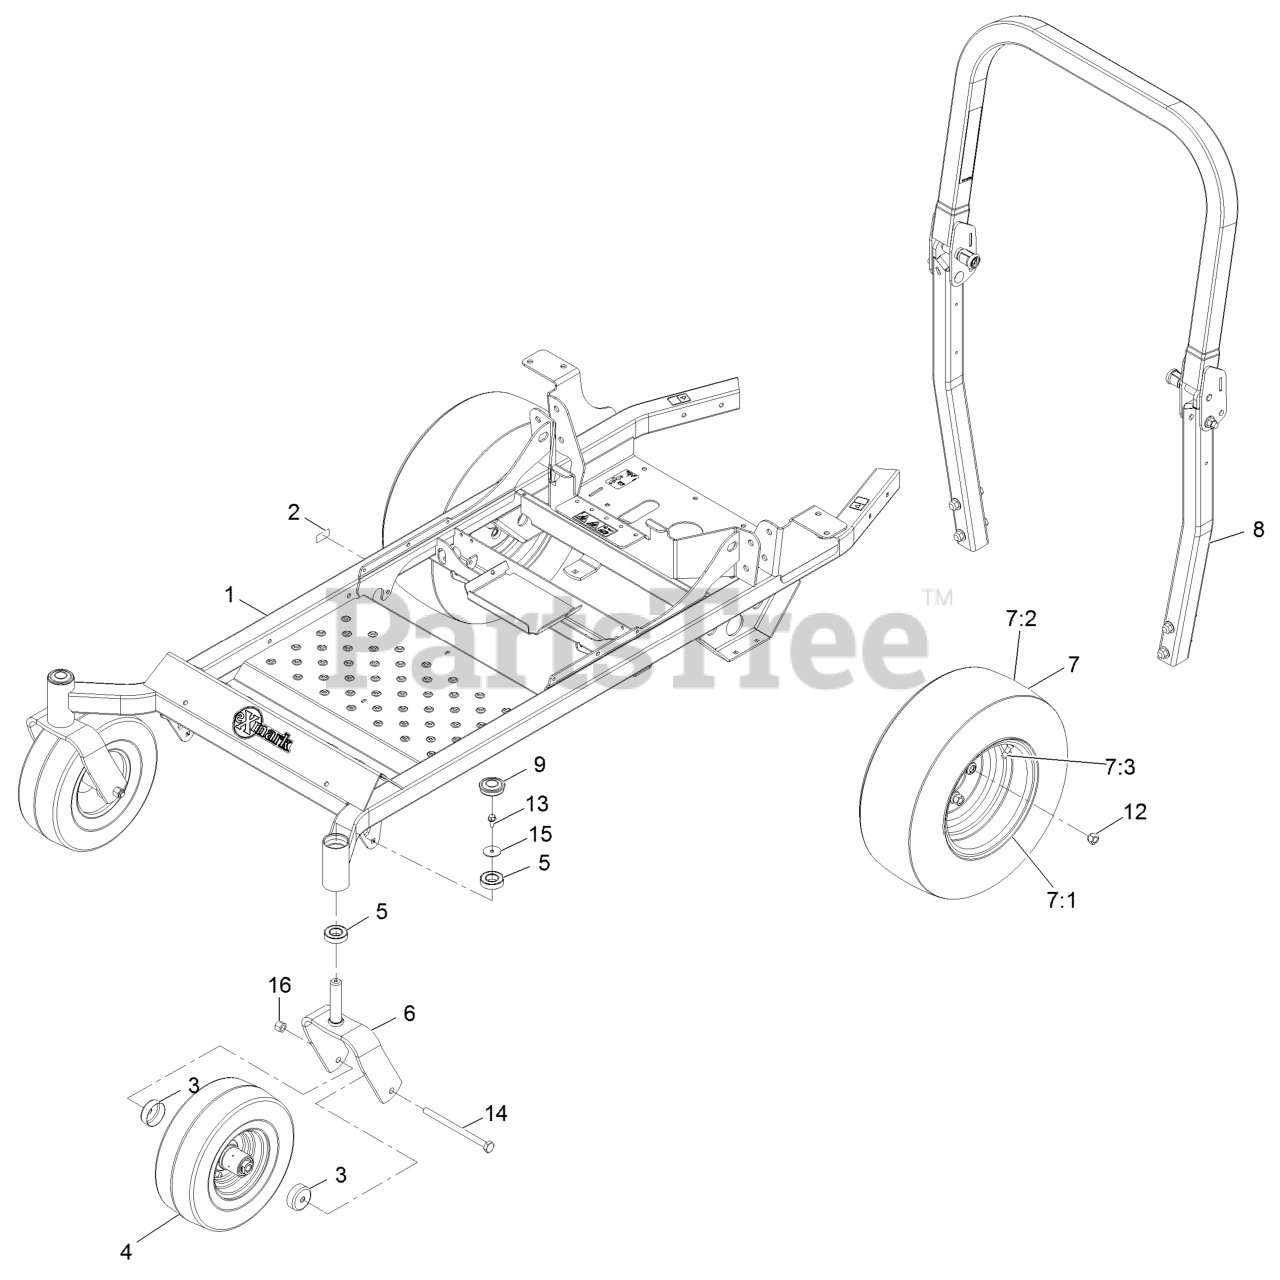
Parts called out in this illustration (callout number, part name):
1	FRAME ASM-48-52
2	Decal-Patent Ttco.Com
3	GUARD-SEAL
4	ASM, WHEEL AND TIRE W/ AX
5	BEARING-BALL
6	WLD,CASTER FORK
7	WHEEL AND TIRE ASM
7:1	WHEEL-12X7, 8 SPOKE 4 ON
7:2	TIRE
7:3	Stem-Valve
8	ASM-ROPS PIONEER
9	CAP-GREASE
12	NUT-LUG
13	SCREW-HHF
14	SCREW-HH
15	WASHER-FLAT
16	NUT-LOCK, NI
